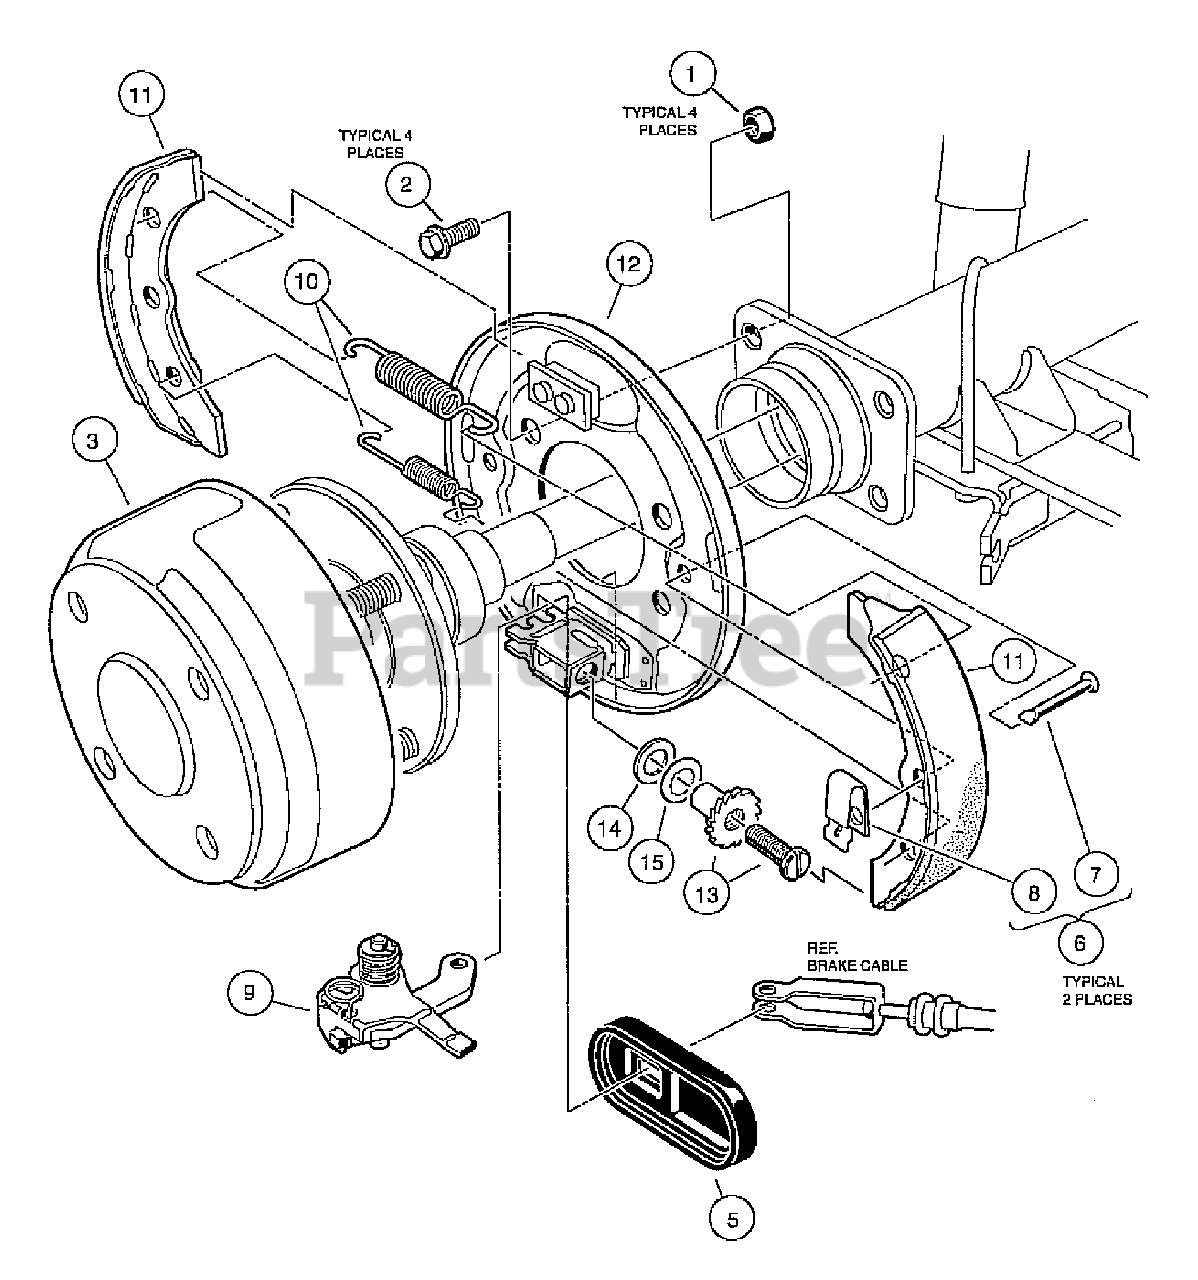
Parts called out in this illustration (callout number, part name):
1	Nut, 5/16-24 Hex Head Cone
2	Bolt, Brake Cluster Mounting
3	Drum W/O Center Hole, Brake
4	Cluster Assembly, Right (Passenger) Brake
5	Dust Cover
6	Kit, Shoe Retainer
8	Shoe Clamp Spring
9	Lever Assembly, S.A. Brake, Right (Passenger)
10	Package, Brake Spring, Self Adjusting
11	Package, Brake Shoe, Self-Adjusting
12	Plate Assembly, Right Brake Backing
13	Adj Mechanism, S.A. Brakes, Right (Passenger)
14	Plate, Washer, Brake, Self-Adjusting
15	Washer, Brake, Self-Adjusting
16	Cluster Assembly, Left Brake
17	Dust Cover
18	Kit, Shoe Retainer
20	Shoe Clamp Spring
21	Lever Assembly, Self-Adjusting Brake, Left
22	Package, Brake Spring, Self-Adjusting
23	Package, Brake Shoe, Self-Adjusting
24	Plate Assembly, Left Brake Backing
25	Adjusting Mechanism, Self-Adjusting Brake, Left
26	Plate, Washer, Brake, Self-Adjusting
27	Washer, Brake, Self-Adjusting
